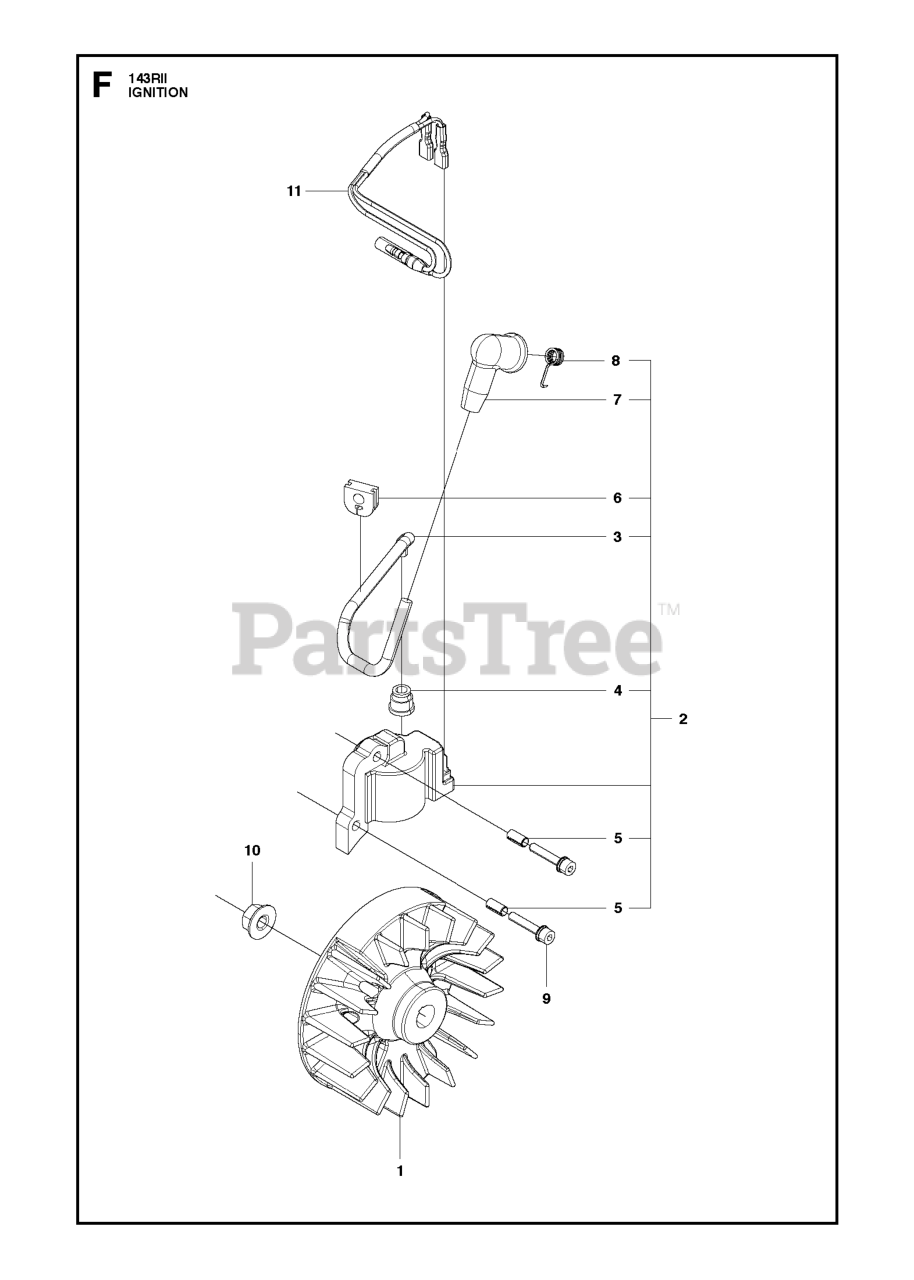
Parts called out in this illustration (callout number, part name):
4	CAP
6	GROMMET
10	NUT
